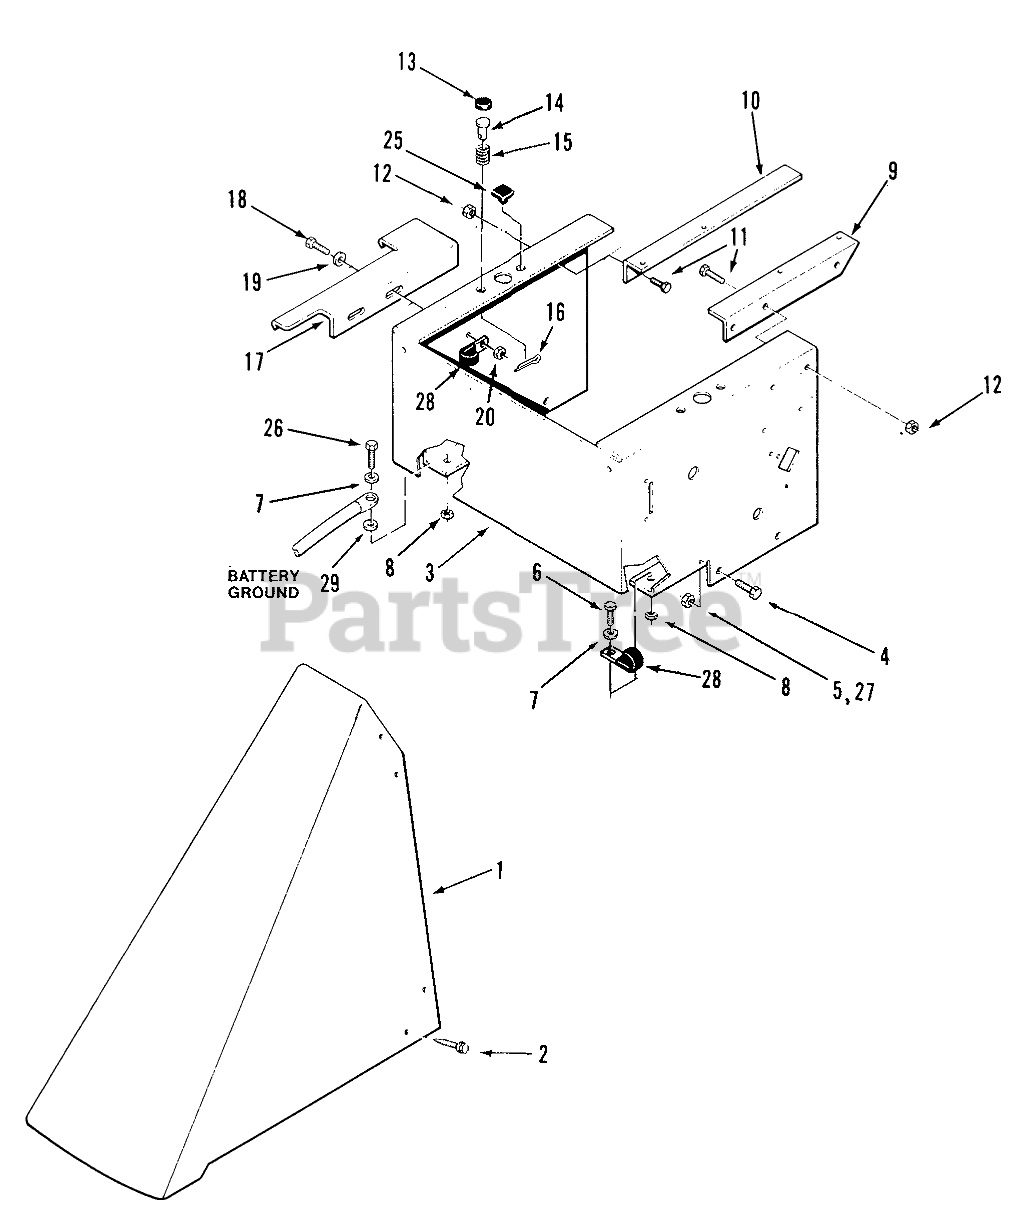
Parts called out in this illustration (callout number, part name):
1	COVER CONSOLE R
2	HEX WASHER STS
3	SUPPORT-SEAT R
4	BOLR HWH 3/8-16X7/8
5	NUT
6	Bolt
7	WASHER 5/16 SAE
8	Nut
9	ANGLE TANK SUPP. R
10	ANGLE TANK SUPP. R
11	H H C S
12	Nut
15	SPRING
16	Cotter Pin
17	PLATE SHIFT R
18	Bolt
19	WASHER 5/16 SAE
20	Nut
25	BUMPER SJ5514 BLACK
26	Bolt
27	Nut
28	CLIP
29	Washer-Lock
